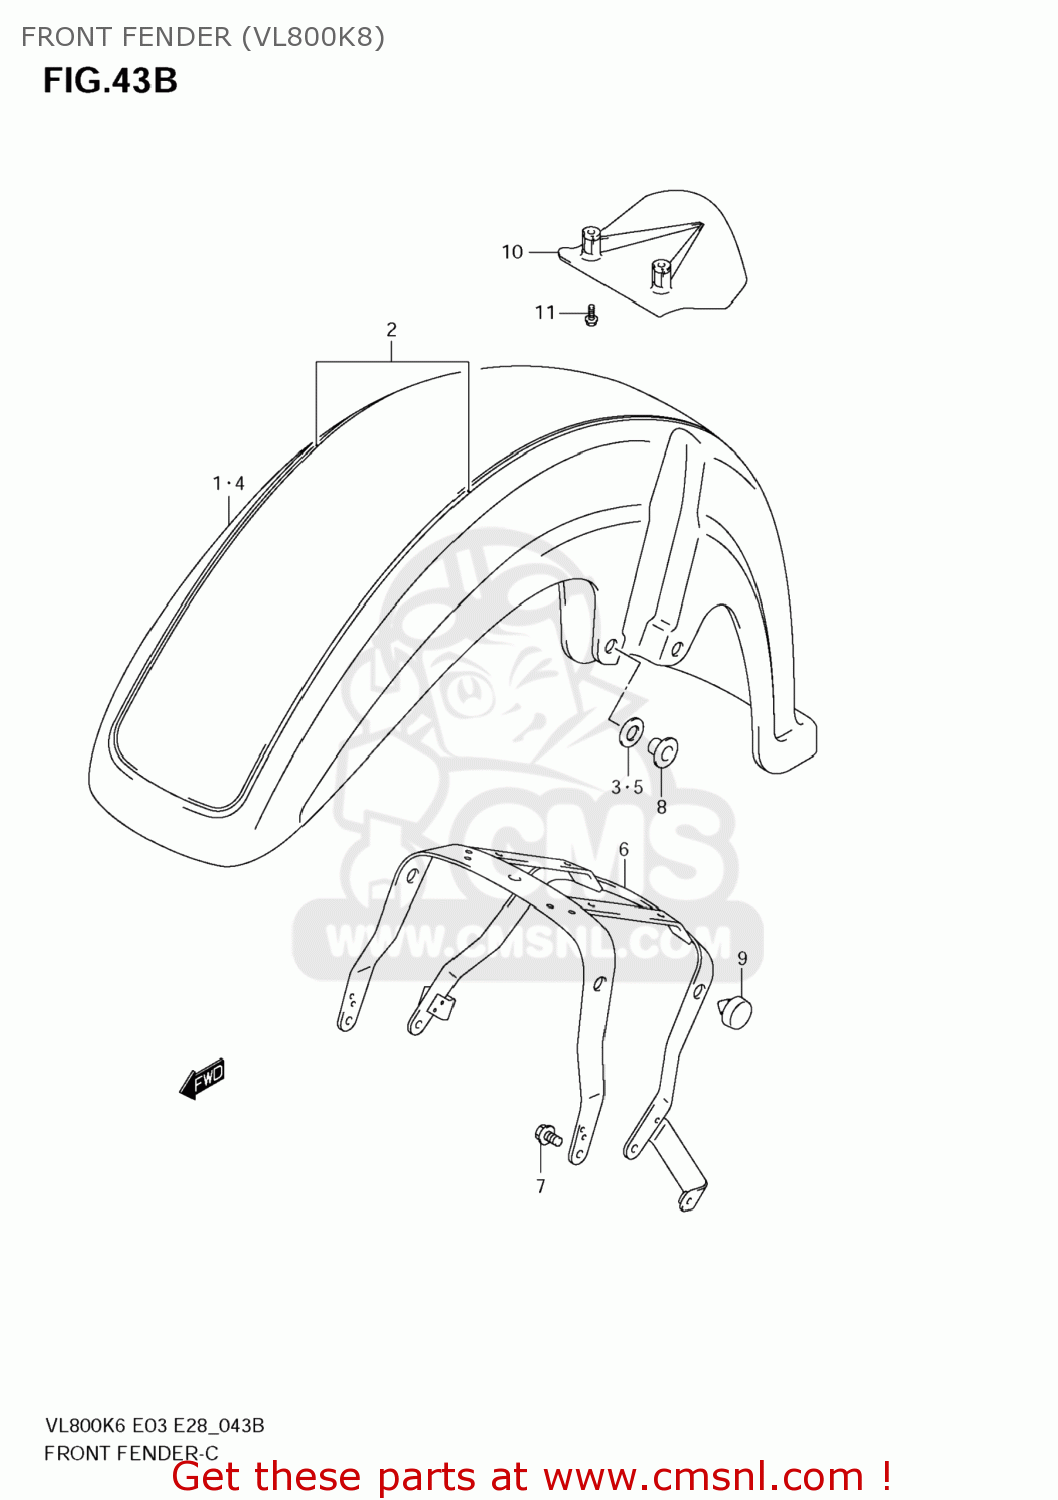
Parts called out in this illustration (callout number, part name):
1	FENDER,FR
2	TAPE SET,FR FENDER
3	CUSHION,FR FENDER
4	FENDER,FR
5	CUSHION,FR FENDER
6	BRACE,FR FENDER
7	BOLT
8	WASHER,FR FENDER
9	CUSHION
10	WING,FR
11	BOLT(6X16)
